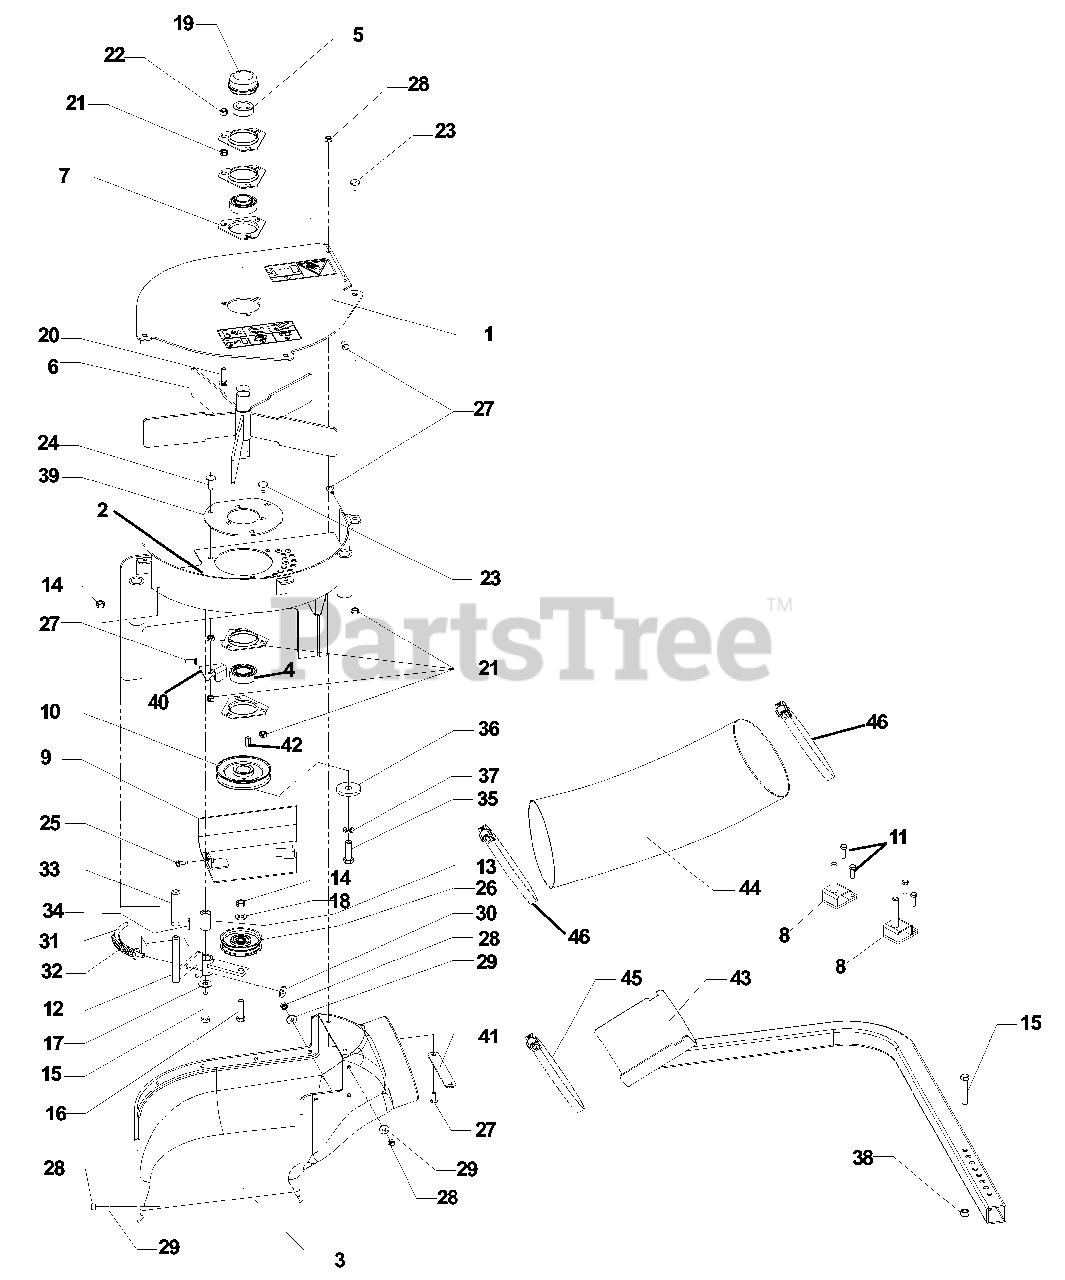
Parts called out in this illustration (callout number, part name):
1	FAN COVER W/DECALS
2	UPPER HOUSING
3	LOWER HOUSING
4	BEARING W/O COLLAR
5	LOCKING COLLAR
6	FAN WLDMT.
8	BLOWER PIN WELDMENT
9	SHEAVE FLOOR
10	SHEAVE, 4"
11	HCS 3/8-16 X 1 1/4
13	SLEEVE BUSHING
14	NUT 3/8 CTR. LOCK
15	HCS 3/8 X 2.25
16	HCS 3/8 X 1.50
17	WASHER 3/8 FLAT
18	WASHER 3/8 SAE
19	GREASE CAP
20	RHSNB 5/16 X 1.25
21	NUT 5/16 CTR. LOCK
22	NUT 5/16 NYLOC
23	RHSNB 5/16 X .625 SHORT NECK
24	RHSNB 5/16 X 1.00
25	SCREW 1/4 X .625 SELF TAP
27	RHSNB 1/4 X .75 SHORT NECK
28	NUT 1/4 NYLOC
29	WASHER 1/4 FLAT
30	WASHER 5/16 FLAT SAE
31	SPRING ROD
33	VINYL GRIP
34	COTTER PIN 3/32 X .750
35	HCS 7/16F X 1.5
36	HEAVY WASHER
37	WASHER 7/16 LOCK
38	NUT 3/8 NYLOC
39	BEARING PLATE
40	BELT GUIDE
42	KEY 1/4 X .75 SQ.
45	HOSE CLAMP
46	OVER CENTER BAND
